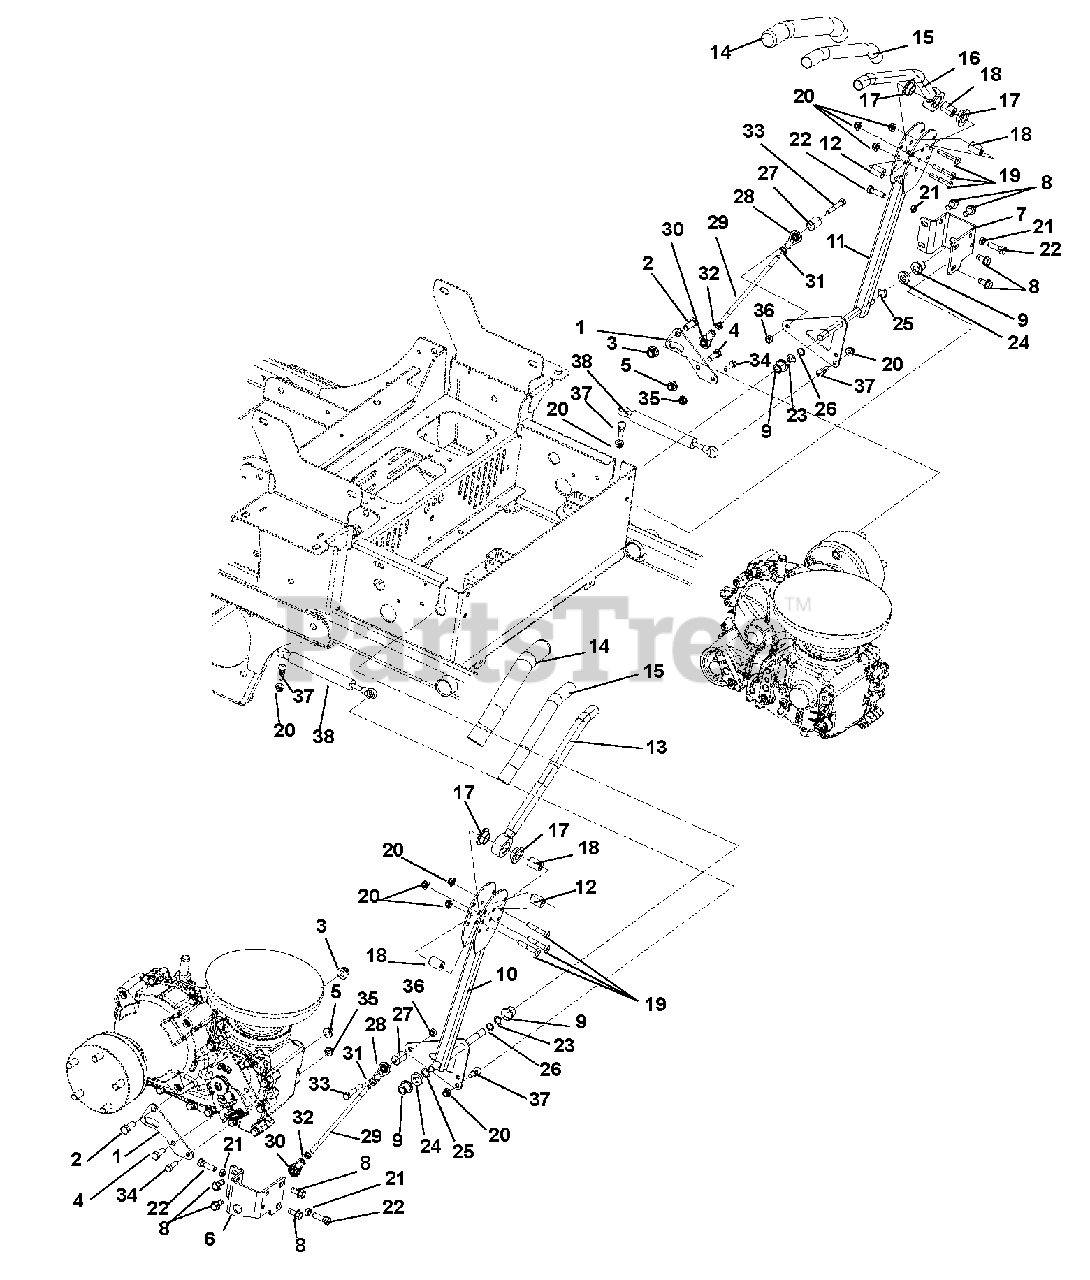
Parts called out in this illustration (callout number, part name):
1	Bracket, Control Mounting
2	Bolt, Hex .44-14 x 1.00 Grade 5
3	Nut, Locking Nylon Flange .44-14
4	Bolt, Hex .38-16 x 1.00 Grade 5
5	Nut, Locking Nylon Flange .38-16
6	Bracket, Right Hand Control Stop
7	Bracket, Left Hand Control Stop
8	Screw, Tapping .38-16 x .75 Hex Washer Head
9	Bushing, Flange .515 x .750 x .745 x 1.00 Nylon
10	Weldment, Right Hand Control Arm
11	Weldment, Left Hand Control Arm
12	Bushing, Eccentric .31 x .75 x .97
13	Handle Weldment Right Hand
14	Grip, Handlebar 1.00 x 1.38 x 11.3
15	Tube, .88ID x 1.00OD x 10.75
16	Handle Weldment Left Hand
17	Bushing, Flange .762 x 1.48 x .44 Nylon
18	Spacer .328 x .76 x 1.01
19	Bolt, Hex .31-18 x 1.75 Grade 5
20	Nut, Locking Nylon Flange .31-18
21	Nut, Hex Jam .375-16
22	Bolt, Hex .38-16 x 1.25 Grade 5
23	Washer, Flat Steel .520 x .810 x .033
24	Spacer .531 x 1.00 x .195
25	Wave Washer .531 x .781 x .125FH
26	Ring, Retaining External .500 x .050
27	Eccentric
28	Alignaball, 5/16 Right Hand Thread
29	Rod, Steering
30	Alignaball, 5/16 Left Hand Thread
31	Nut, Jam .31-24
32	Nut, Jam Left Hand .31-24
33	Bolt, Hex .31-18 x 2.00 Grade 5
34	Bolt, Hex .31-18 x 1.00 Grade 5
35	Nut, Locking Top Flange .31-18
36	Nut, Locking Center .31-18
37	Stud, Ball
38	Damper
